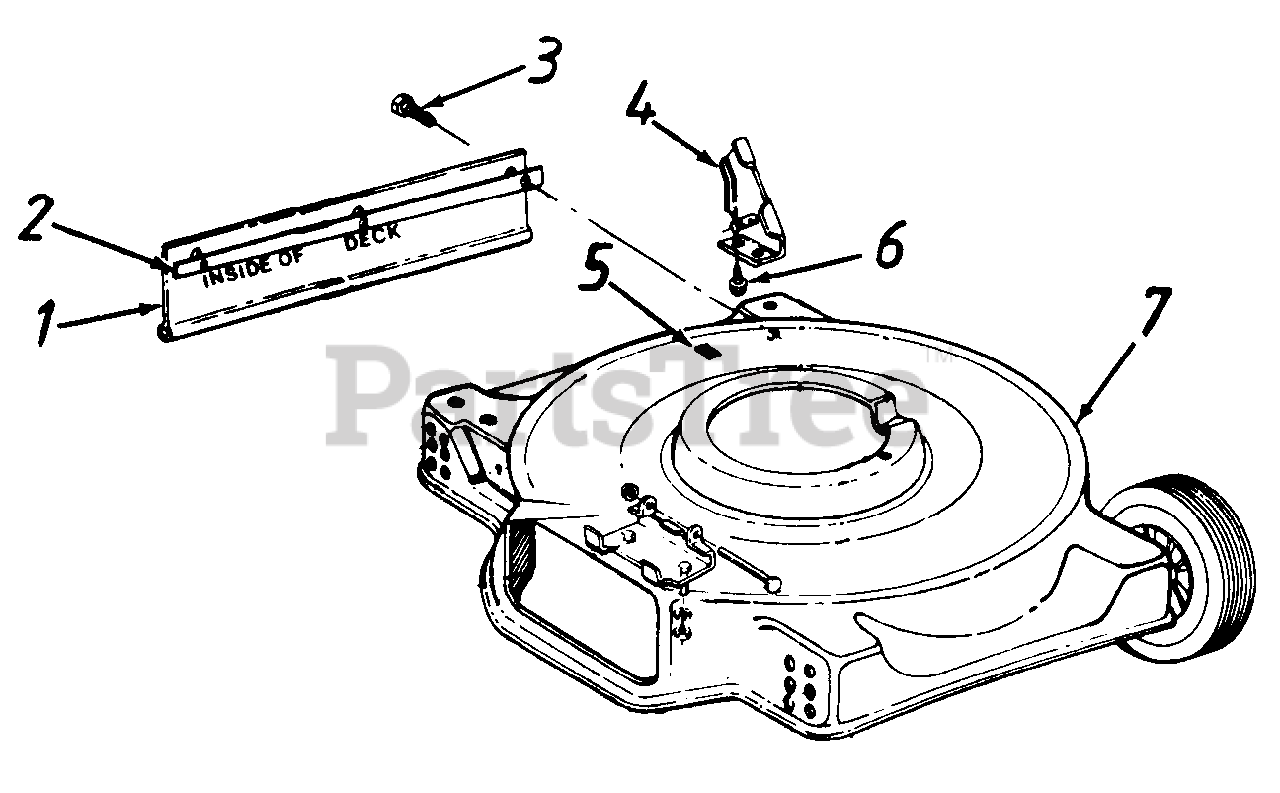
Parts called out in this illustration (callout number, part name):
1	Rear Flap Assembly
2	Retainer Strip
3	Hex AB-Tap Scr. 1/4" x .62" Lg.
4	Handle Mount Brkt.-L.H.
5	Plastic Plug
6	Hex Self-Tap Scr. 5/16-18 x .5" Lg.
